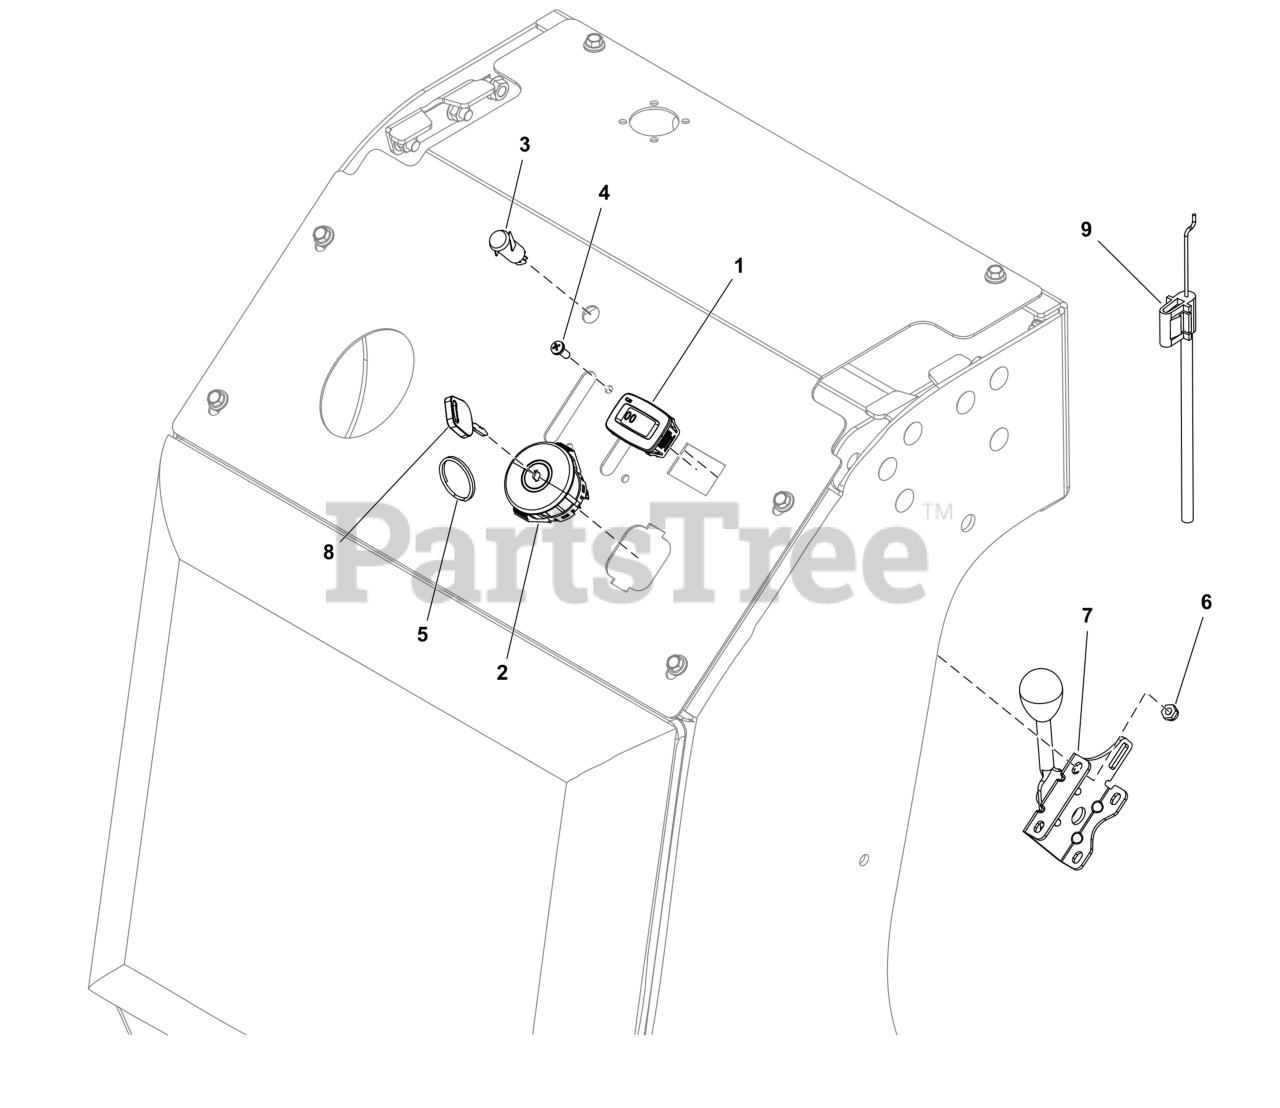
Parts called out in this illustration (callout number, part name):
1	METER, HOUR
2	SWITCH, Ignition
3	LIGHT, INDICATOR
4	SCREW, #10-24 X 1/2" ROUND PHILLIPS
7	LEVER, THROTTLE CONTROL
8	KEY-IGNITIOM W/PLASTI
9	CABLE, THROTTLE, 31"
